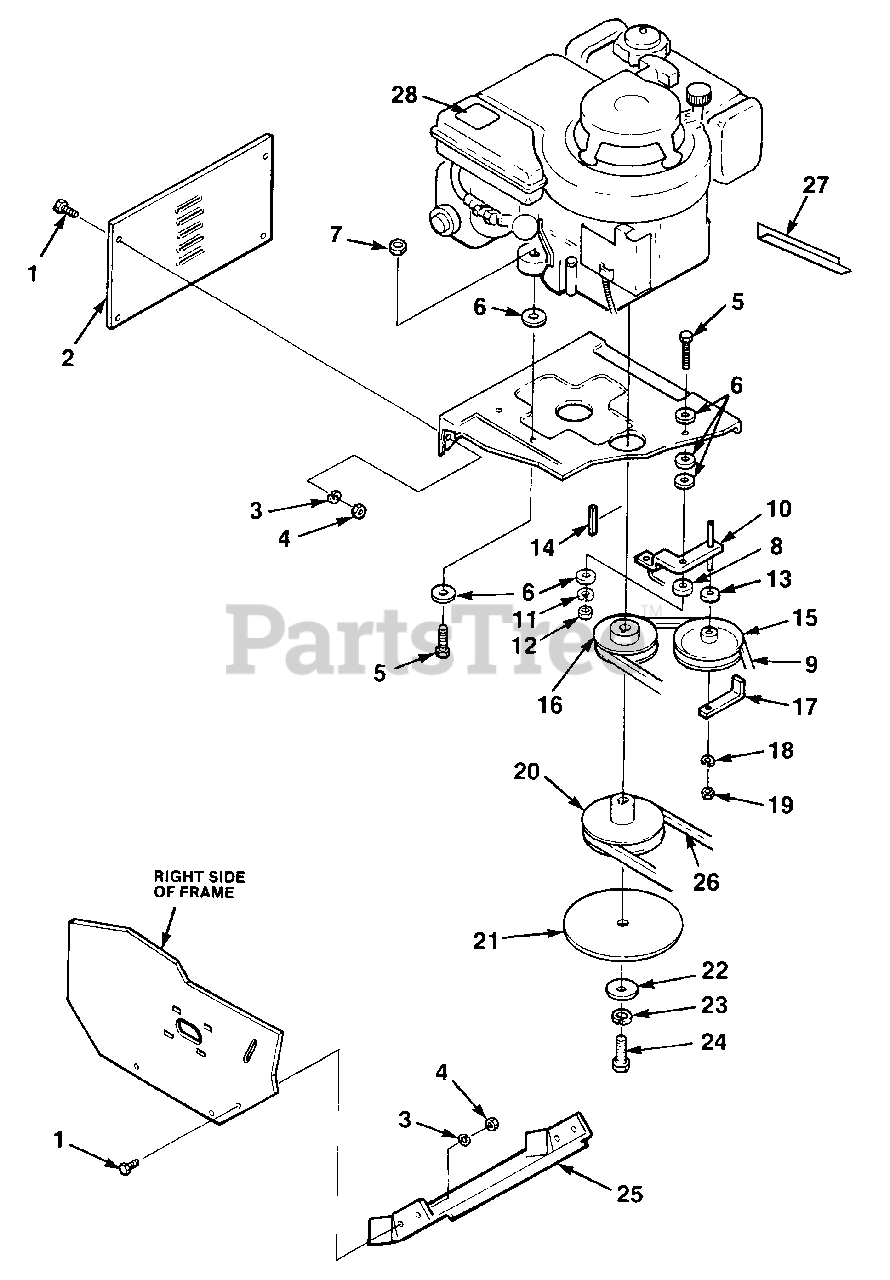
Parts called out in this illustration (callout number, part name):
1	BOLT- Hex centerlock 1/4-20 x .625
2	PANEL- Rear
3	WASHER- Lock 1/4-20
4	NUT- Hex
5	SCREW- Hex centerlock 5/16-18 x 1 1/2"
6	WASHER- Engine
7	NUT- Hex centerlock 5/16-18
9	BELT- Transmission
10	ARM- Idler
11	WASHER- Lock 5/16"
12	NUT- Hex centerlock 5/16-18
13	WASHER- Plain 3/8"
15	PULLEY- Idler
16	PULLEY- Traction
17	GUIDE- Belt
18	WASHER- Lock 1/4"
19	NUT- Hex centerlock 1/4-20 x 1"
20	PULLEY- Deck
21	DISC- Belt guide
22	RETAINER- Clutch
23	WASHER- Lock 7/16"
24	BOLT- Hex centerlock 7/16-20 x 2"
25	PAN- Bottom
26	BELT- Mower deck
28	DECAL- Warning
